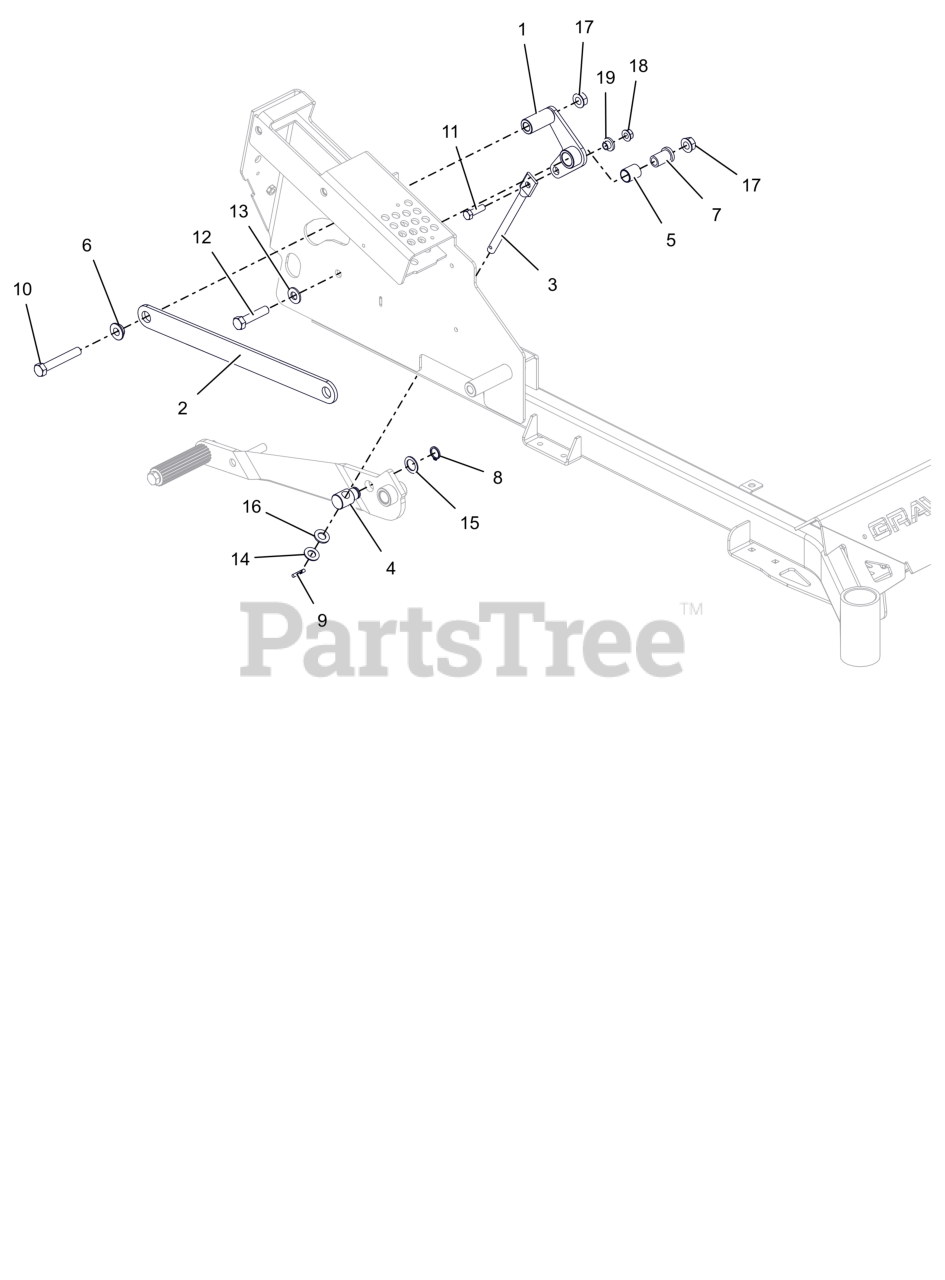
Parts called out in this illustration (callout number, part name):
1	WLDMT, PIVOT BRKT
2	LINK,36" DECK LIFT FOOT ASSIST
3	LINK, HOC FOOT
4	TRUNNION,DECK LIFT FOOT ASSIST
5	BRG, .750 X .875 X 1.000
6	BSHG, FLG .515X.750X.360X1.12
7	BSHG-FLG .515X.746X1.290X1.000
8	RG-RTNG-EXT .689X.078
9	PIN-GRV .188X1.00 TP E
10	BLT,HEX .50-13X3.25 G5 ZCC
11	BLT, HEX .38-16X1.25 G5 ZCC
12	BLT, HEX .50-13X2.25 G5 ZCC
13	WSHR,FLT .531X1.062X.095 ZCC
14	WSHR, FLT .531X1.00X.063 ZCC
15	WSHR, FLT .754X1.125X.062 ZCC
16	WSHR, RUBBER .332X1.000X.094
17	NUT-LK-CTR-FLG .500-13 GG ZCC
18	NUT-LK-CTR-FLG .375-16 GF ZCC
19	BSHG-FLG .385X.500X.875X.406
